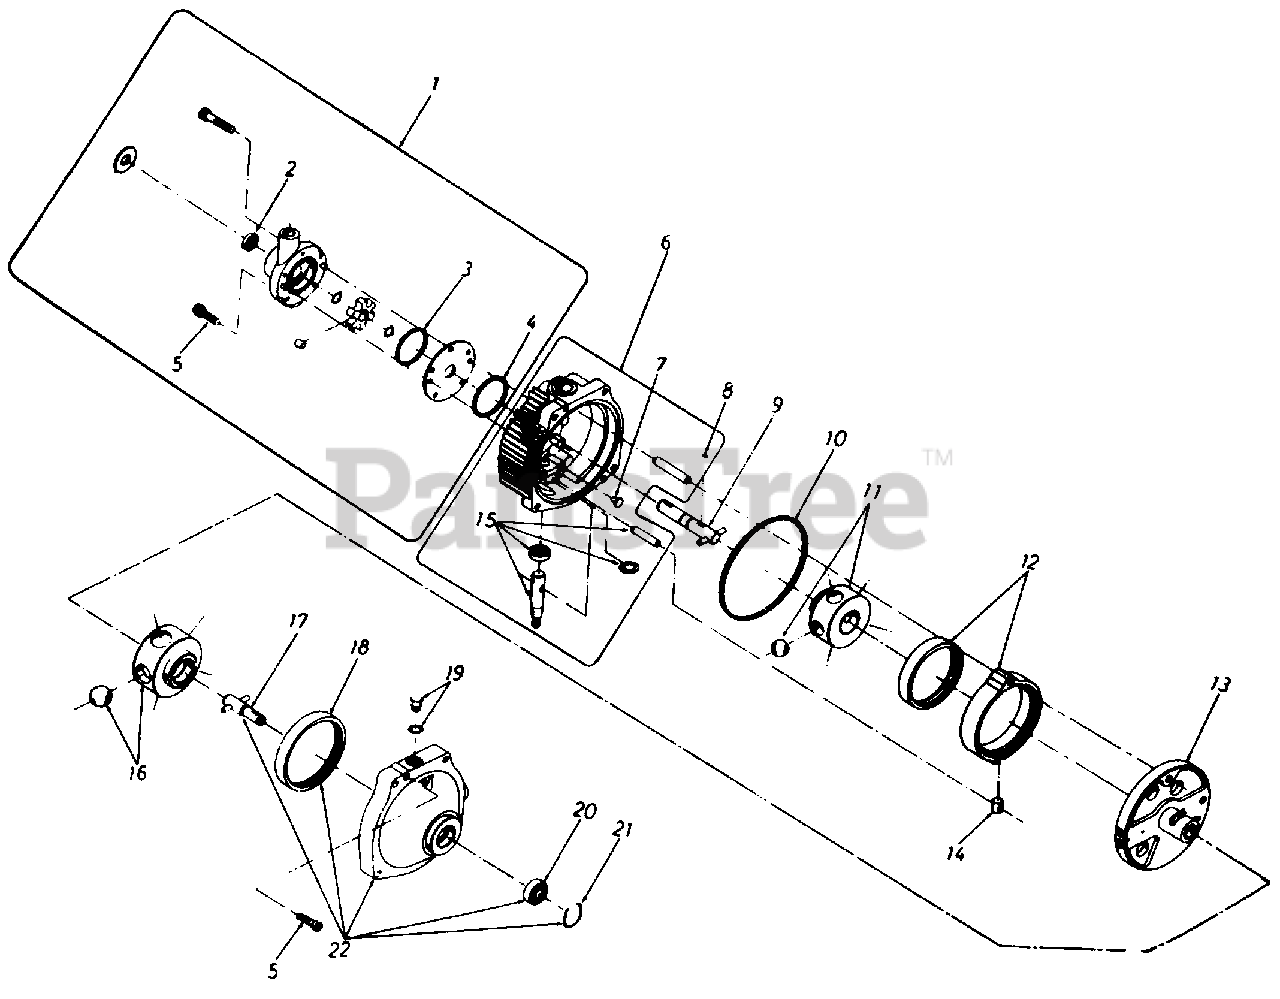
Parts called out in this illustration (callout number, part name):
1	Charge Pump Kit
2	Oil Seal
3	Square Cut Seal Ring .036
4	Square Cut Seal Ring .308
5	Socket Head Cap Screw 5/16-18 x 1.25" Long
6	Cover Subassembly
8	Drive Pin
9	Input Shaft Subassembly
10	Square Cut Seal Ring .166
11	Pump Rotor - Ball Subassembly
12	Cam Ring Subassembly
13	Pintle Subassembly
14	Cam Ring Insert
15	Control Shaft Kit
16	Motor Rotor - Ball Subassembly
17	Output Shaft Subassembly
18	Motor Race
19	"O"-Ring Plug Subassembly
20	Ball Bearing (Output)
21	Retaining Ring
22	Body Subassembly
